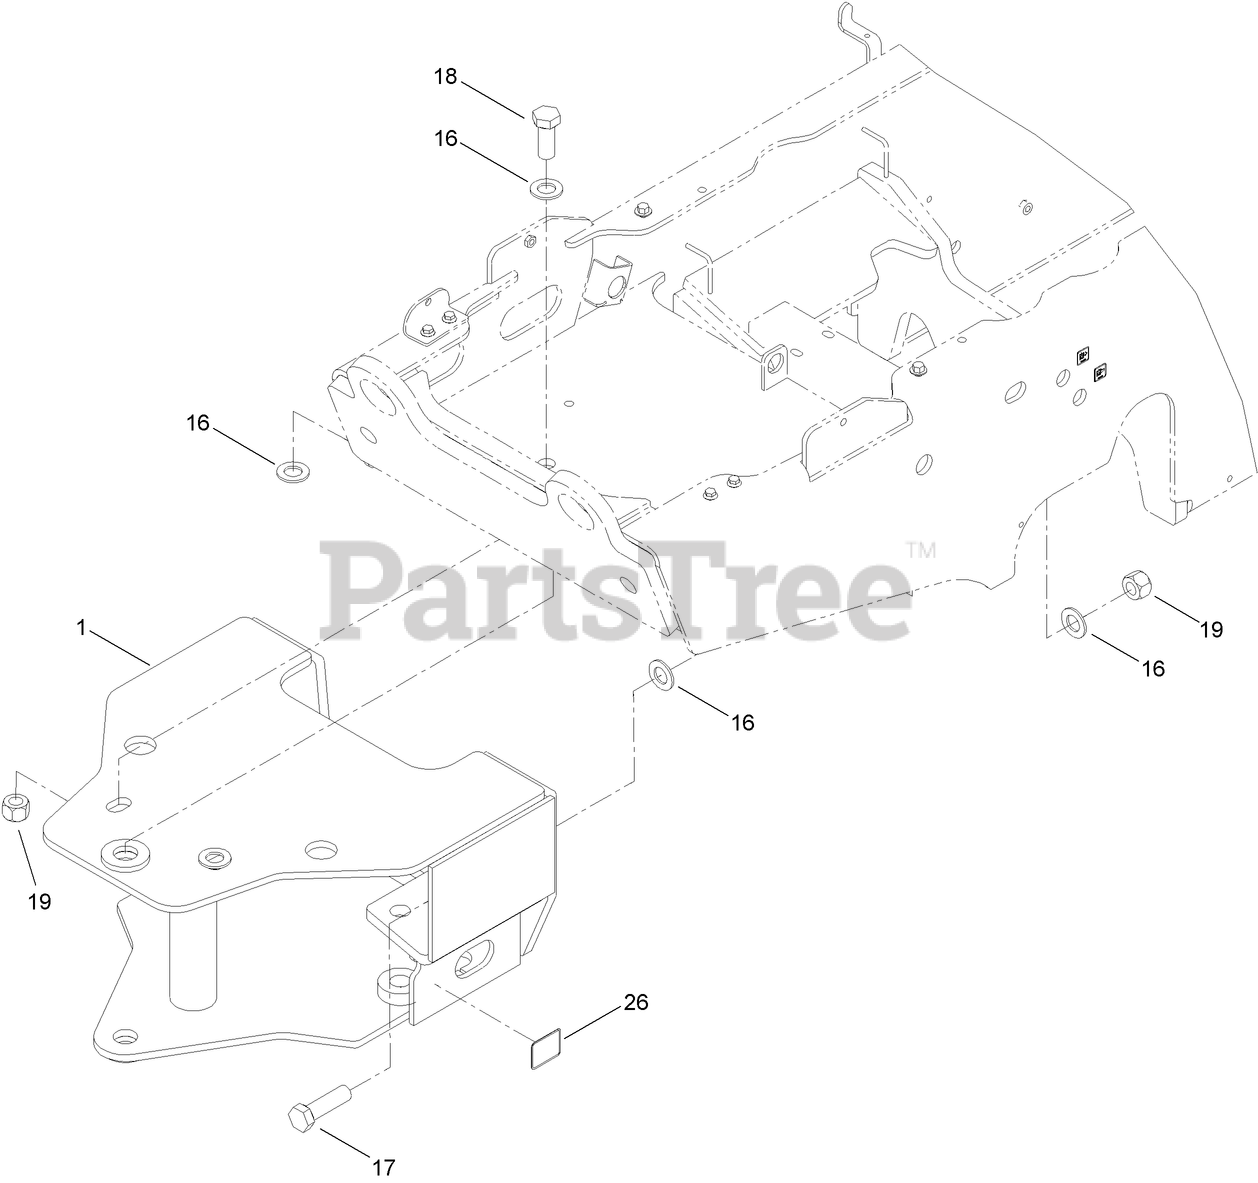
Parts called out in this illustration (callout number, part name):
1	FRAME-BLADE, BACKFILL
17	SCREW-CAP, HH
26	DECAL-TIE DOWN
